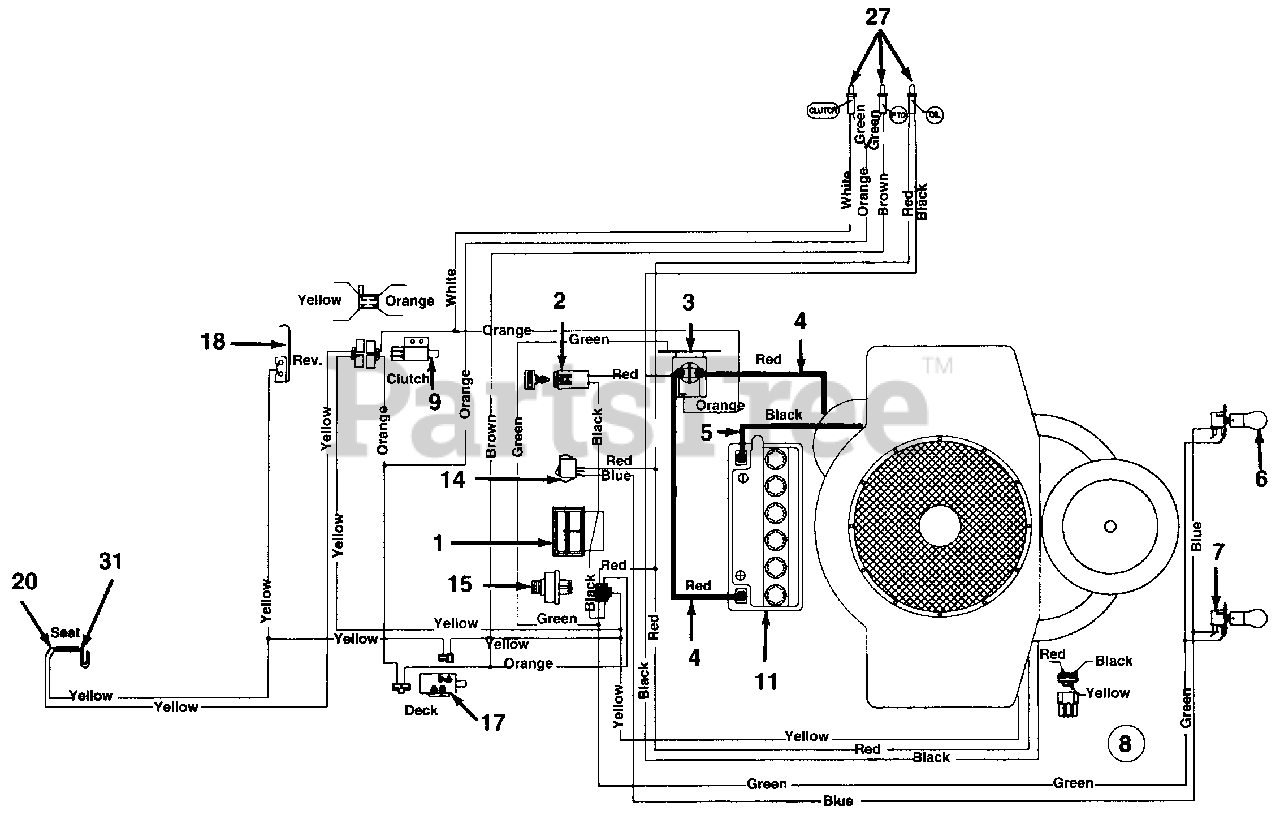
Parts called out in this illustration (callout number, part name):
1	Ammeter
2	Fuse 20 Amp
3	Solenoid
4	Wire
5	6 Ga. Black Wire 17" Lg.
6	Bulb
7	Socket
8	Wire Harness
9	Safety Switch (Clutch)
11	Battery
14	Light Switch
15	Safety Switch (Deck)
17	Spring Lever
18	Safety Switch (Seat)
20	Safety Switch (Seat)
27	Bulb
31	Safety Switch (Seat)
